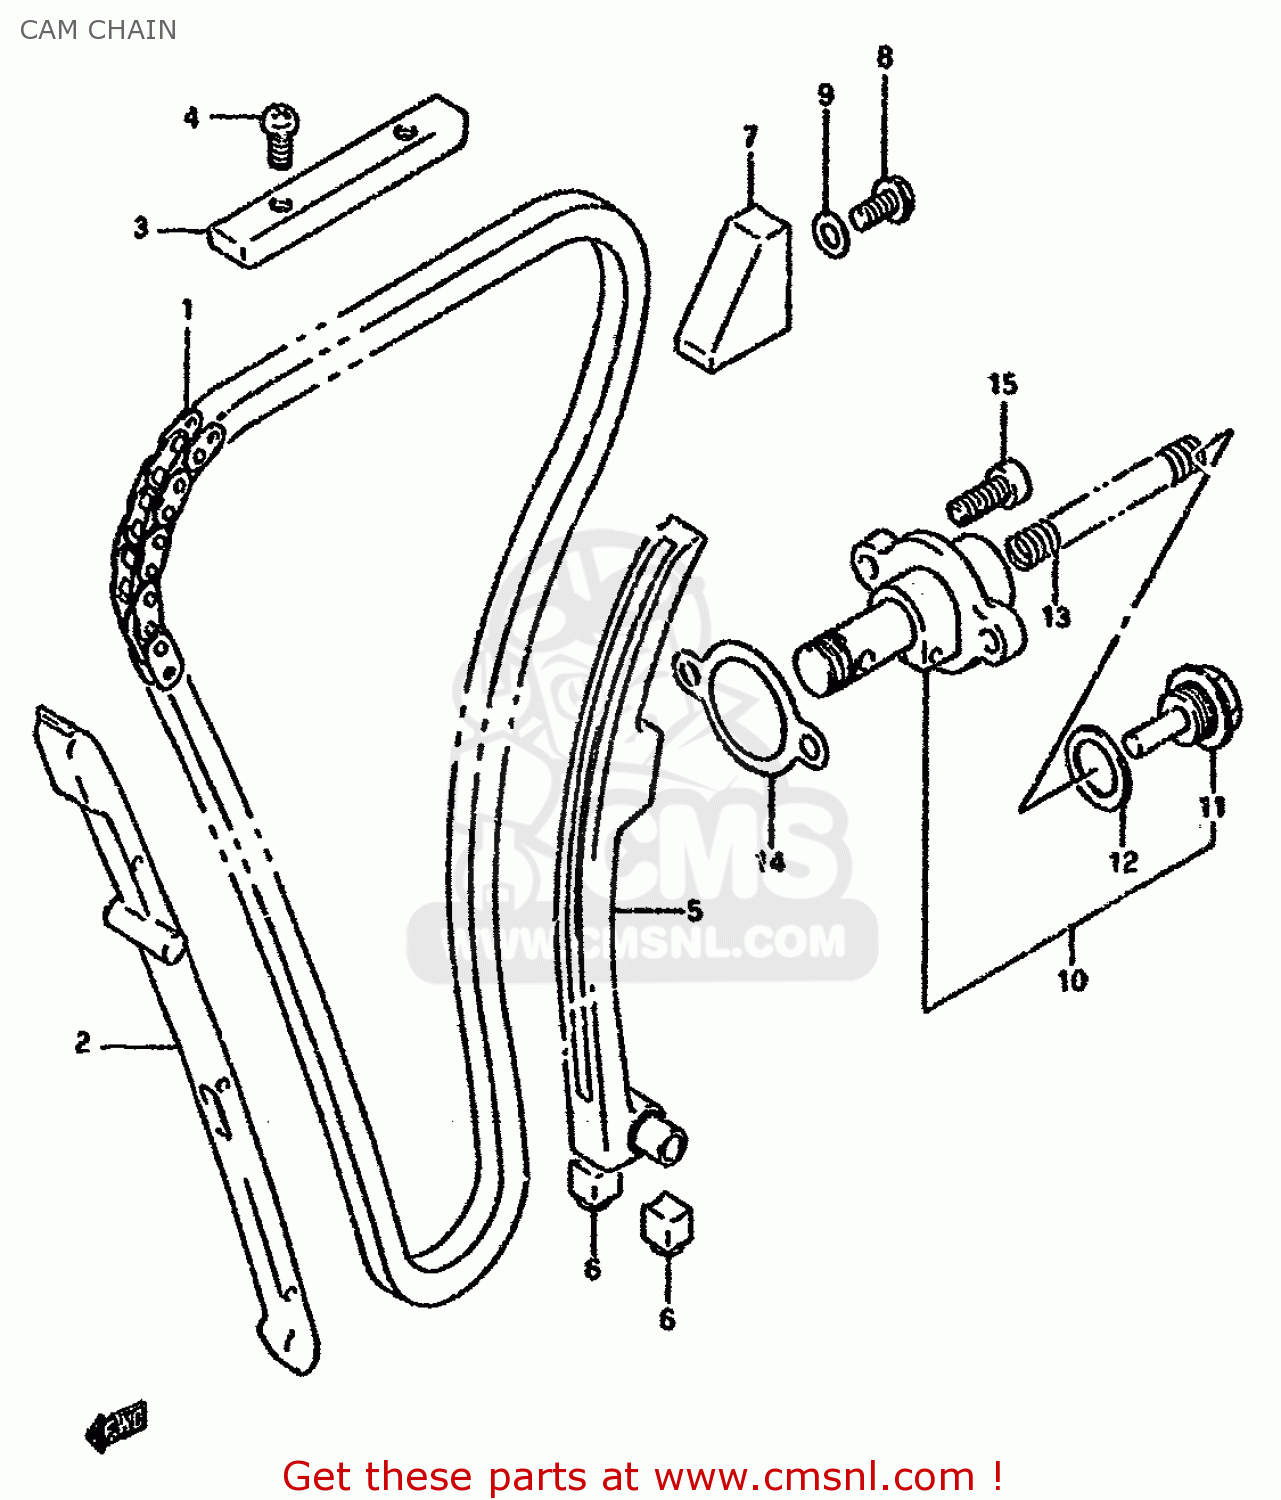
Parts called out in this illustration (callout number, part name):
1	CHAIN,CAMSHAFT DRIVE
2	GUIDE,CAM CHAIN NO.1
3	GUIDE,CAM CHAIN NO.2
4	SCREW
5	TENSIONER,CAM CHAIN
6	CUSHION,CAM CHAIN TENSIONER
7	GUIDE,CAM CHAIN NO.3
8	BOLT
9	GASKET(5.8X13X1.2) (NAS)
10	ADJUSTER ASSEMBLY,TENSIONER
11	PLUG
12	GASKET (NAS)
13	SPRING
14	GASKET,TENSIONER ADJUSTER (NAS)
15	BOLT
